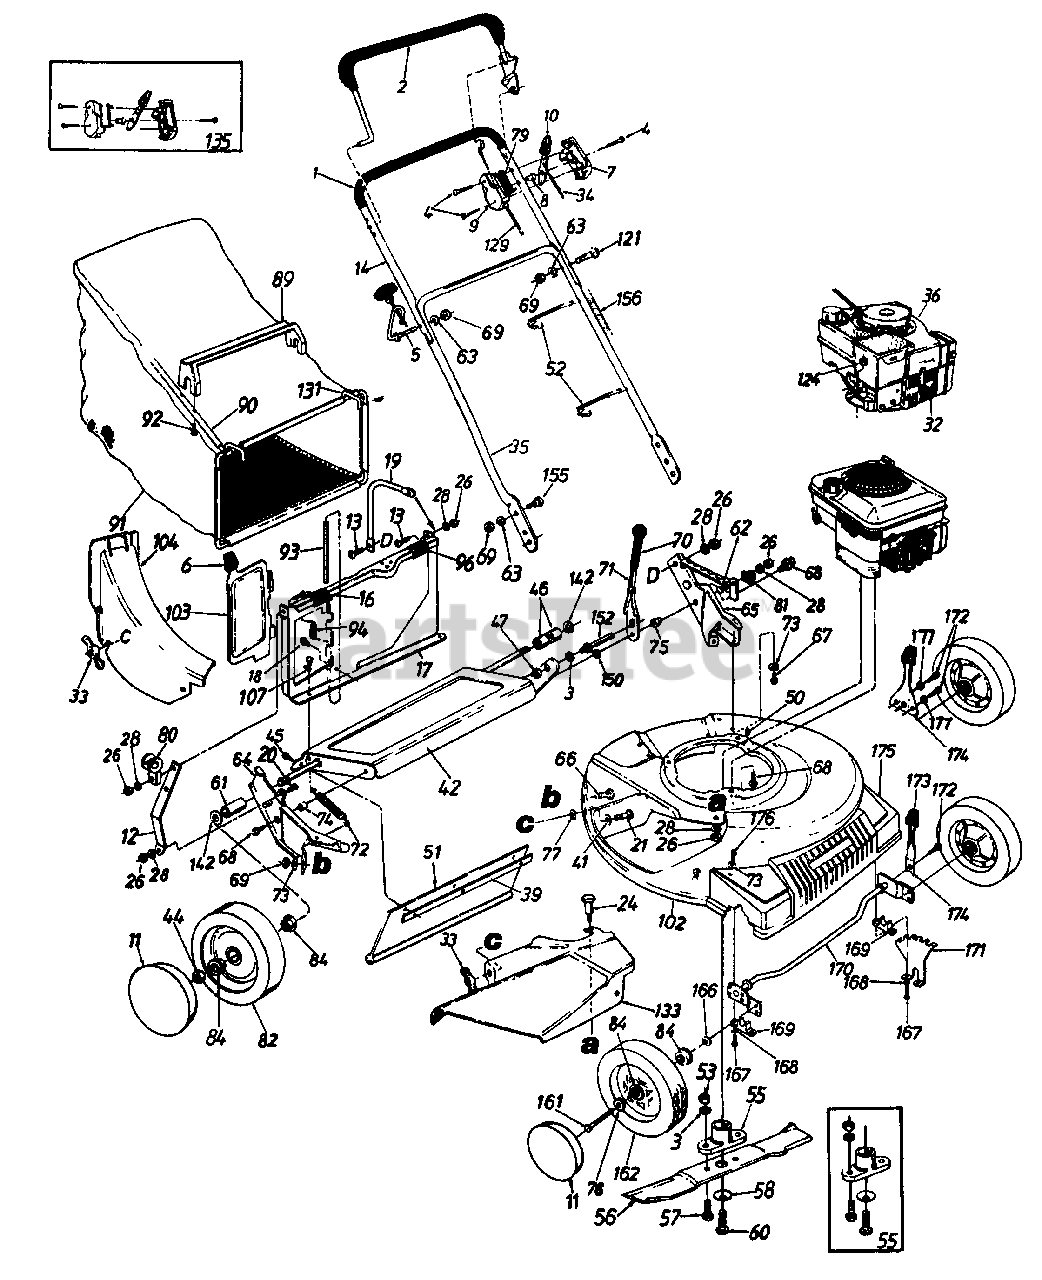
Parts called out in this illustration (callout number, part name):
1	Foam Grip
2	Control Handle Ass'y. L.H.
3	L-Wash. 3/8" I.D.
4	Truss Mach. Scr. #12 x 1.5"
5	Rope Guide Bolt
6	Door Grip
7	Control Panel Half
8	Control Disc Pin
9	Clutch Panel Half
10	Throttle Control Lever
11	Hub Cap
13	Truss Mach. Scr. 1/4-20 x .62"
14	Upper Handle
16	Truss Mach. Scr. 1/4-20 x .75"
19	Catcher Panel Support Arm
20	Hex Bolt 1/4-20 x .62" Lg.
21	Carriage Bolt 1/4-20 x .62"
24	Shoulder Bolt .312 Dia. x .18 Lg. Special
26	Hex Nut 1/4-20 Thd.
28	L-Wash. 1/4" I.D.
32	Spark Plug Insulator
33	Wing Nut w/Washer
34	Throttle Control Ass'y. Comp. 61"
35	Lower Handle
36	Engine
39	Retaining Strip
41	Fl-Wash. .344" I.D. x .62"
45	Hex AB-Tap Scr. 1/4 X .62"
46	Spacer.526" I.D.
47	Hex Jam Nut 3/8-24 Thd.
51	Rear Flap
52	Cable Tie
53	Hex Nut 3/8-24 Thd.
55	Blade Adapter Kit
56	21" Blade
57	Hex Bolt 3/8-24 x 1" Lg.
58	Bell-Wash. .46" I.D. x 1.12"
60	Hex Bolt 7/16-20 x 1.5" Grade 5
61	Sleeve.526" I.D.
62	Truss Mach. Scr. 1/4-20 x .75" Lg.
63	L-Wash. 5/16" I.D.
64	R.H. Handle Wheel Brkt. Ass'y.
65	L.H. Handle Wheel Brkt. Ass'y.
66	Carriage Bolt 5/16-18 x .62"
67	Hex B-Tap Scr. 5/16-18
68	Hex TT-Tap Scr. 3/8-16
69	Hex Nut 5/16-18 Thd.
71	Height Adj. Lever
72	Extension Spring 3.80" Lg.
73	Bell-Wash. 5/16" I.D.
74	Spacer.383" I.D.
75	Shld. Spacer.5" Dia.
76	Wave Wash. .53" I.D. x .78"
77	Bolt Retainer 1/4 x .50" O.D.
79	Control Label
80	Rope Guide
81	Clamp
82	Wheel Ass'y. Comp.
84	Flange Ball Bearing 1/2" I.D.
89	Bag Handle
91	Grass Bag
92	Hex AB-Tap Scr. #12 x 1.25" Lg.
93	Chute Rod .188" Dia.
94	Torsion Spring
96	Panel Clip
104	Top Discharge Chute Ass'y.
107	Hex Bolt 1/4-20 x .50" Lg.
121	Curved Carr. Bolt 5/16-18 x 1.75" Lg.
124	Hex Nut 3/8 x 16 Thd.
129	Control Cable 46"
133	Side Chute Deflector Ass'y.
135	Kit Control Housing Comp.
142	Fl-Wash. .510" I.D. x .75"
150	Fl-Wash. 3/8" I.D. x 1.0"
152	Shld. Pin 3/8-24 x 1.43" Lg.
155	Truss Mach. Scr. 5/16-18 x .75"
156	Plastic Tubing 24" Lg.
161	Front Axle Bolt
162	Wheel Ass'y. Comp.
166	Bell-Wash. .400" I.D. x .88
167	Hex B-Tap Scr. 1/4-20
168	L-Wash. 1/4" I.D.
169	Block Bushing
170	Axle Ass'y.
172	Hex TT-Tap Scr. 1/4-20 x .50"
173	Knob
174	Spring Lever (With 1 hole only)
175	Plastic Front End
176	Truss B-Tap Scr. 5/16 x .75"
177	Ext. L-Wash. 1/4" I.D.
